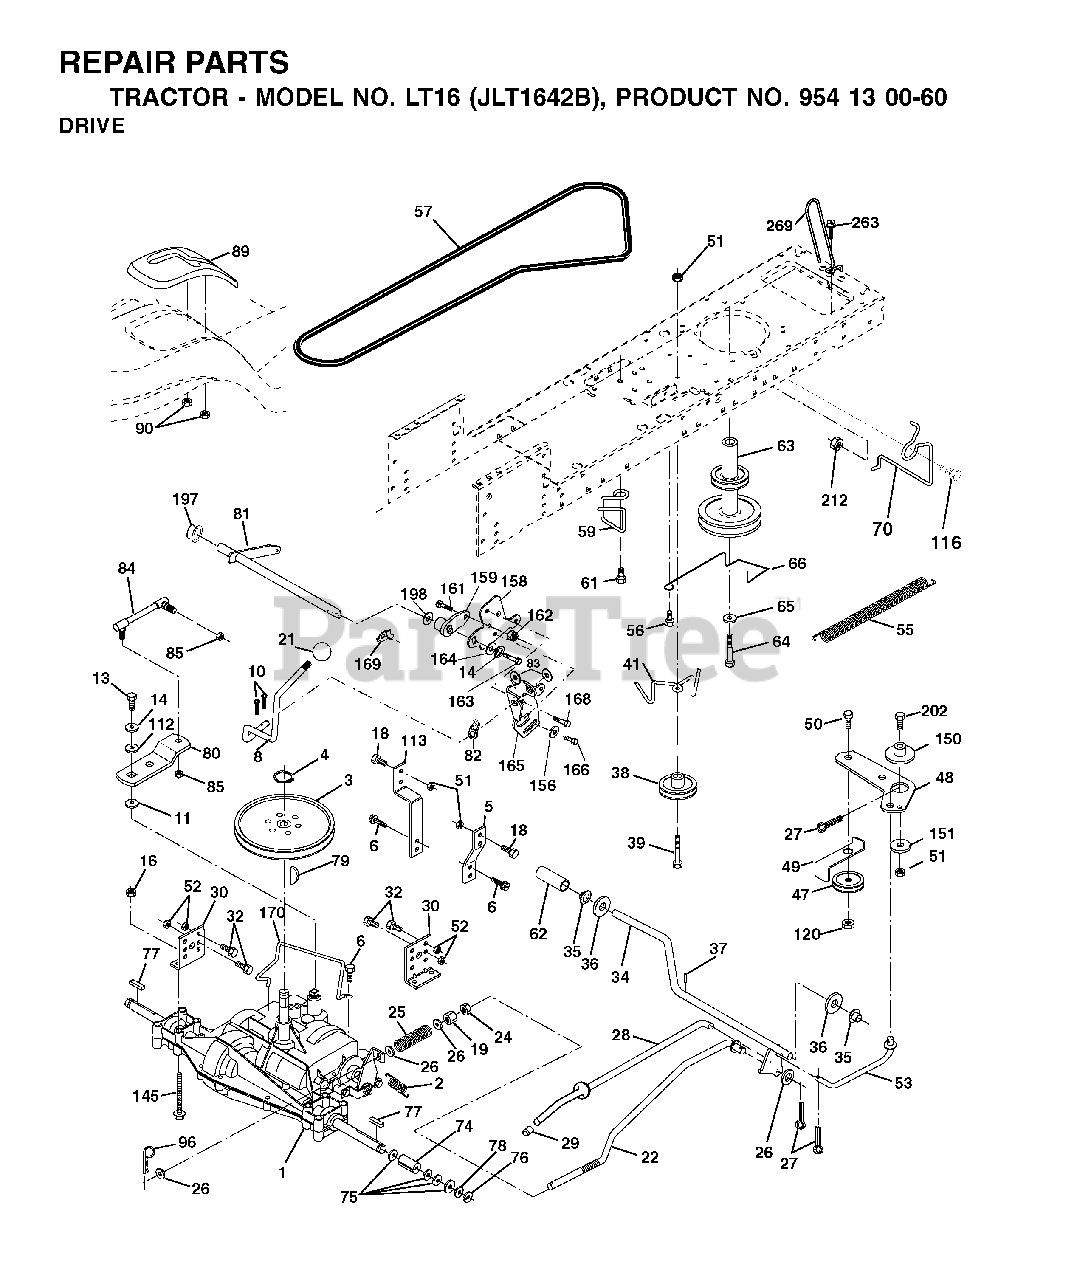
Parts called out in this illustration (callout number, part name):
2	SPRING,BRAKE RETURN
3	PULLEY TRANS
4	RETAINING RING LT
5	STRAP TORQUE
6	SCREW 5/16"
8	ROD SHIFT FENDER ADJUST STLT
10	PIN COTTER
11	WASH-SHFT PLT LT
13	BOLT 1/4-28X3/4
14	LOCKWASHER
16	NUT.71038.31-18.HEX.NYLOCK
19	NUT
21	PISTOL KNOB
22	ROD BRAKE
24	NUT
25	SPRING ROD LT
27	COTTER PIN
28	ROD, PARKING BRAKE
29	PLUNGER CAP
30	BRKT, TRNSXLE MNT 20"
32	BOLT
34	SHAFT, FOOT PEDAL
35	BEARING.NYLON
36	WASHER LT
37	DRIVE PIN
38	PULLEY IDLER COMPOSITE
39	BOLT
41	KEEPER, BELT IDLER
47	IDLER PULLEY
48	BELLCRANK, CLUTCH
49	RETAIN BELT
50	BOLT.3/8-16X1.50
51	LOCKNUT
52	LOCKNUT
53	LINK, CLUTCH LT
55	SPRING, RETURN LT
56	SCREW.3/8-16
57	V-BELT
59	KEEPER, BELT CENTER
61	SCREW 3/8-16X.875
62	PEDAL COVER T
64	BOLT
65	LOCKWASHER
66	KEEPER BELT ENGINE
74	SPACER AXLE
76	E-RING LT
77	SQUARE KEY
80	ARM SHIFT
82	SHIFT SPRING
83	WASHER
85	NUT LOCK CENTER 1/4 -28 FNTHD
89	CONSOLE.SHIFT.STLT.6SP.BLACK
96	RETAINER M
112	WASHER LT
113	STRAP TORQUE LH LT
116	BOLT D
120	NUT LOCK FLG 3/8-16 UNC
150	SPACER, RETAINER
151	WASHER 12/32X2X10GA
156	WASHER.SRRTD.5/16
158	BRACKET
159	HUB
161	BOLT
162	NUT.CROWNLOCK.1/4
165	RP BRACKET
168	BOLT.SHOULDER.5/16-18X
169	PLATE.FASTENING.CROSS.SHAFT
170	KEEPER BELT T/A
197	NYLINER SNAP 5/8" ID
198	WASHER.NYL.7/8IDX.105"HYD CR
202	BOLT
212	NUT
263	SCREW, 3/8-16X3/4
